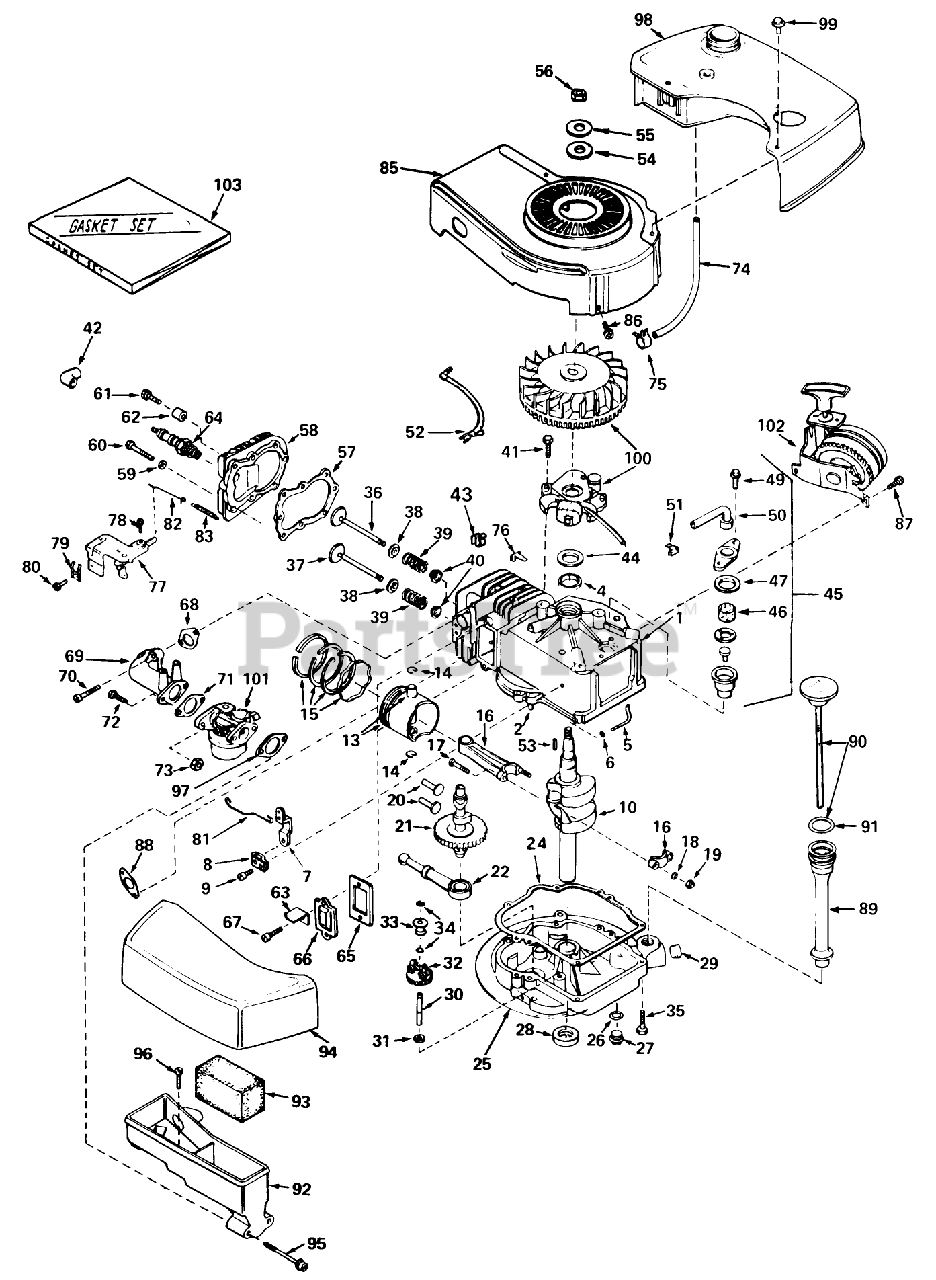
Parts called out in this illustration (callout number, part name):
1	Cylinder Assy. (Incl. Ref. #2, 4 105)
2	Pin-Dowel
4	OIL SEAL
5	Rod, Governor (Incl. No. 36)
6	Washer-Flat
7	Governor Lever
8	Clamp-Lever, Governor
9	Screw
10	Crankshaft
13	Piston Pin Assembly (Incl. 2 of No. 14) (.010 Oversize)
13	Piston Pin Assembly (Incl. 2 of No. 14) (.020 Oversize)
14	Ring-Retaining, Piston Pin
15	Ring Set Piston (Std.)
15	Ring Set Piston (.010 Oversize)
15	Ring Set Piston (.020 Oversize)
16	Rod Assy., Connecting (Incl. Ref. #17)
17	Bolt, Connecting
18	Washer
19	LOCKNUT
20	Lifter-Valve
21	Camshaft(Mech.Comp. Release)
22	Oil Pump ASM
24	Gasket, Mounting
25	Filter, Air Cleaner
26	Gasket-Oil Drain
27	Plug Oil Drain
28	Seal Oil
29	Plug Oil Drain
30	Shaft-Governor
31	Washer-Flat
32	Governor Gear ASM
33	Spool-Governor
34	Ring-Retaining
35	Screw (1/4-20 x 1-1/4)
36	Valve, Intake (Incl. Ref. #38, 39 40) (Std.)
36	Valve, Exhaust (1/32" Oversize) (Incl. Nos. 8, 9 10)
37	Valve, Exhaust (Standard) (Incl. Nos. 8, 9 10)
37	Valve, Exhaust (1/32" Oversize) (Incl. Nos. 38, 39 40)
38	Cap-Upper Valve Spring
39	Spring-Valve
40	Cap-Valve, Spring
41	Screw
42	Cover-Spark Plug
43	51004 GIL ROTARY TI
44	Gasket Stator
45	Breather Assy. (Incl. Ref. #46, 47, 49, 50 51 )
46	Element-Breather
47	Gasket-Breather
49	Screw, Hex Hd. w/Conical
50	Tube, Breaker
51	Clip, Breather
52	Wire Ground
53	Key-Flywheel
54	Washer Flat
55	Washer-Spring
56	Hex Nut
57	63573 GIL 42 SNWTHW
58	Head Cylinder
59	Washer
60	Screw
61	Screw Hex Hd. Cap
62	Space
63	Retainer Clip
64	Plug, Spark (Champion RCJ-8)
65	Gasket-Breather
66	Cover-Valve
67	Screw
68	Gasket, Intake
69	Pipe, Intake
70	Screw (1/4-20 x 1)
71	Gasket-Carburetor
73	Nut and Lock Washer (1/4-28)
74	Line-Fuel
75	Clamp-Line, Fuel
76	Clip-Wire
77	Control Assy., Speed (Incl. Nos, 76, 78 89)
78	Screw (10-24 x 3/4)
79	Conduit
80	Screw (10-32 x 3/8)
81	Link Governor
82	Link Governor Spring
83	Spring Governor
85	Housing, Blower
86	Screw
87	Screw (1/4-20 x 1/2)
88	Gasket Exhaust
89	Tube Fill
90	Dipstick, Oil (Incl. Ref. #101)(Twist Lock)
91	O-Ring
92	Body Air Cleaner
93	Filer, Air
94	Cove, Air Cleaner
95	Screw Fil Hd.
96	Screw, Hex Hd.
97	Gasket-Air Cleaner
98	Tank Fuel
99	Screw (10-32 x 35/64)
100	Magneto
101	Carburetor (Incl. No. 71)
102	Starter, Side Mount
103	53024/VAR.16HP O/P
